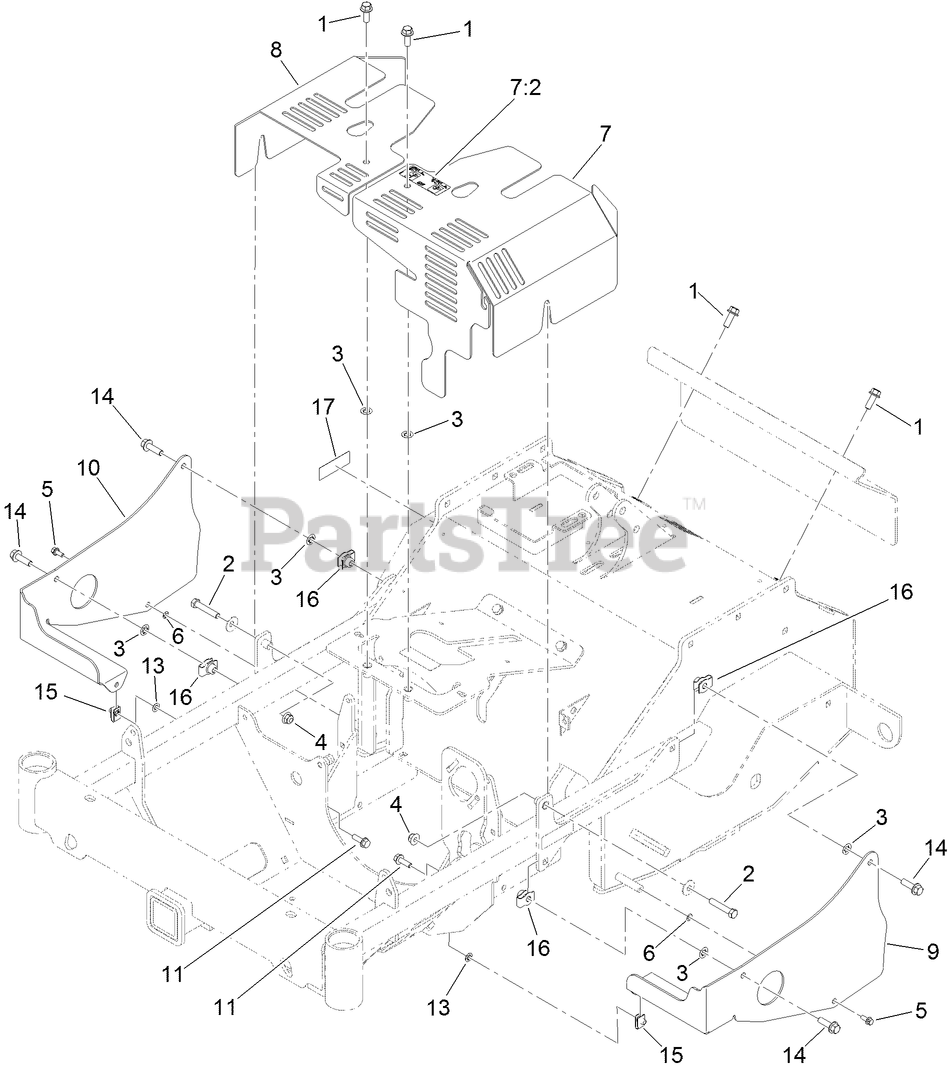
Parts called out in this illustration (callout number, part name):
1	SCREW-HHF
2	SCREW-HH
3	NUT-PUSH
4	NUT-HF, NI
5	SCREW-HHF
6	PUSHNUT-RETAINER, BOLT
7	HYDRO COVER ASM
7:2	DECAL-RELEASE, DRIVE
8	COVER-HYDRO
9	GUARD-CHAIN
10	GUARD-CHAIN
11	SCREW-HHF
13	RING-RETAINING, BOLT
14	SCREW-HHF
15	NUT-U
17	DECAL-SOUND
